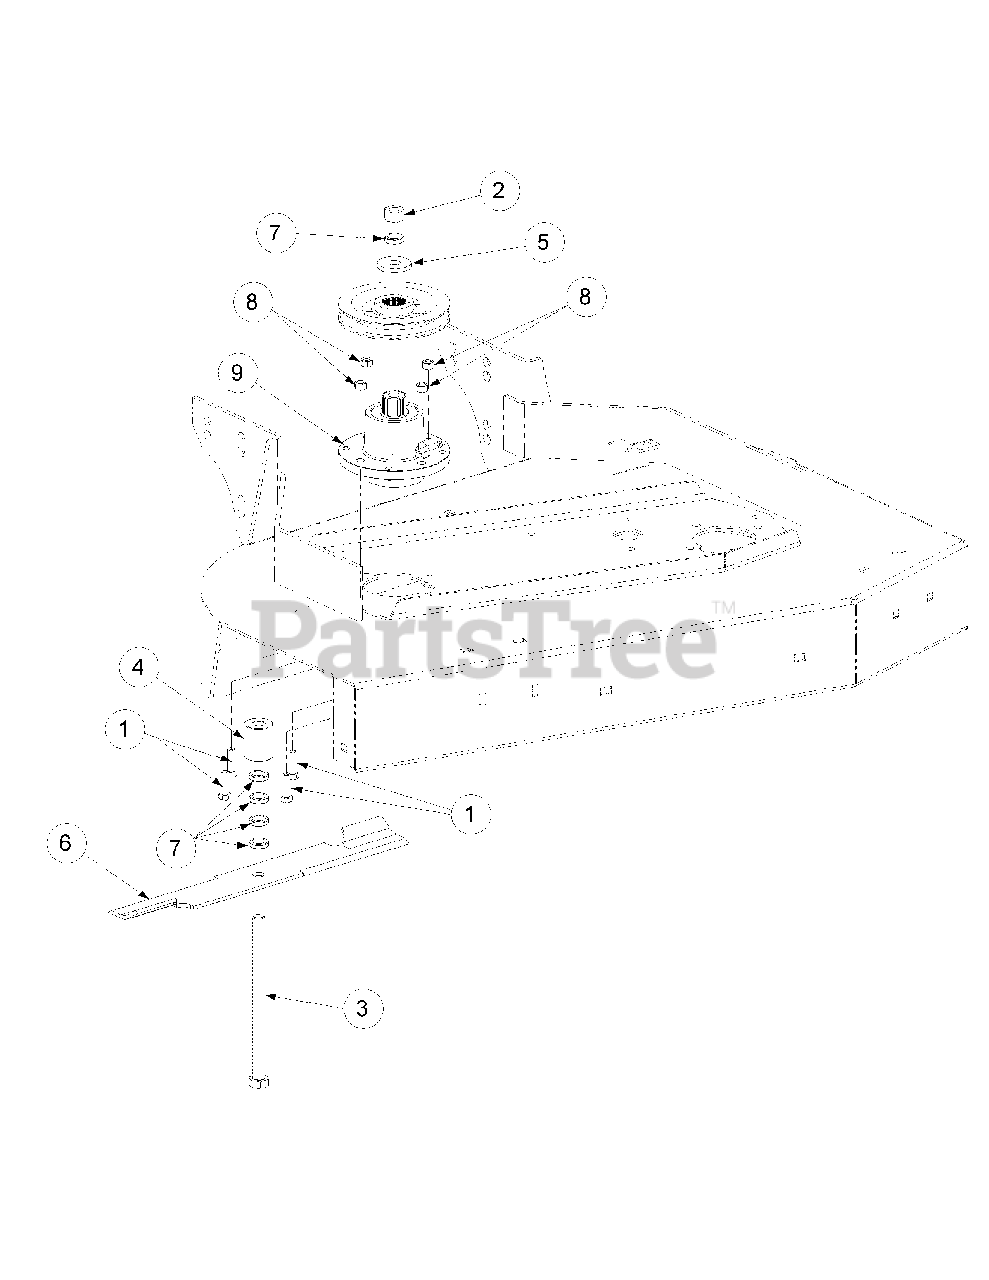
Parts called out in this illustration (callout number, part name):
1	Hex Cap Screw, 3/8-16 x 1-1/4
2	Hex Nut, 5/8-11
3	Hex Cap Screw, 5/8-11 x 9
4	Blade Spacer, .630 x 1.500 x 1.850
5	Flat Washer, .656 ID x 1.313 OD
6	18" Rotary Blade
7	Blade Spacer, 5/8 ID, 1/4 Thick
8	Nut, Hex Flange Lock, 3/8-16
9	Spindle Assembly
